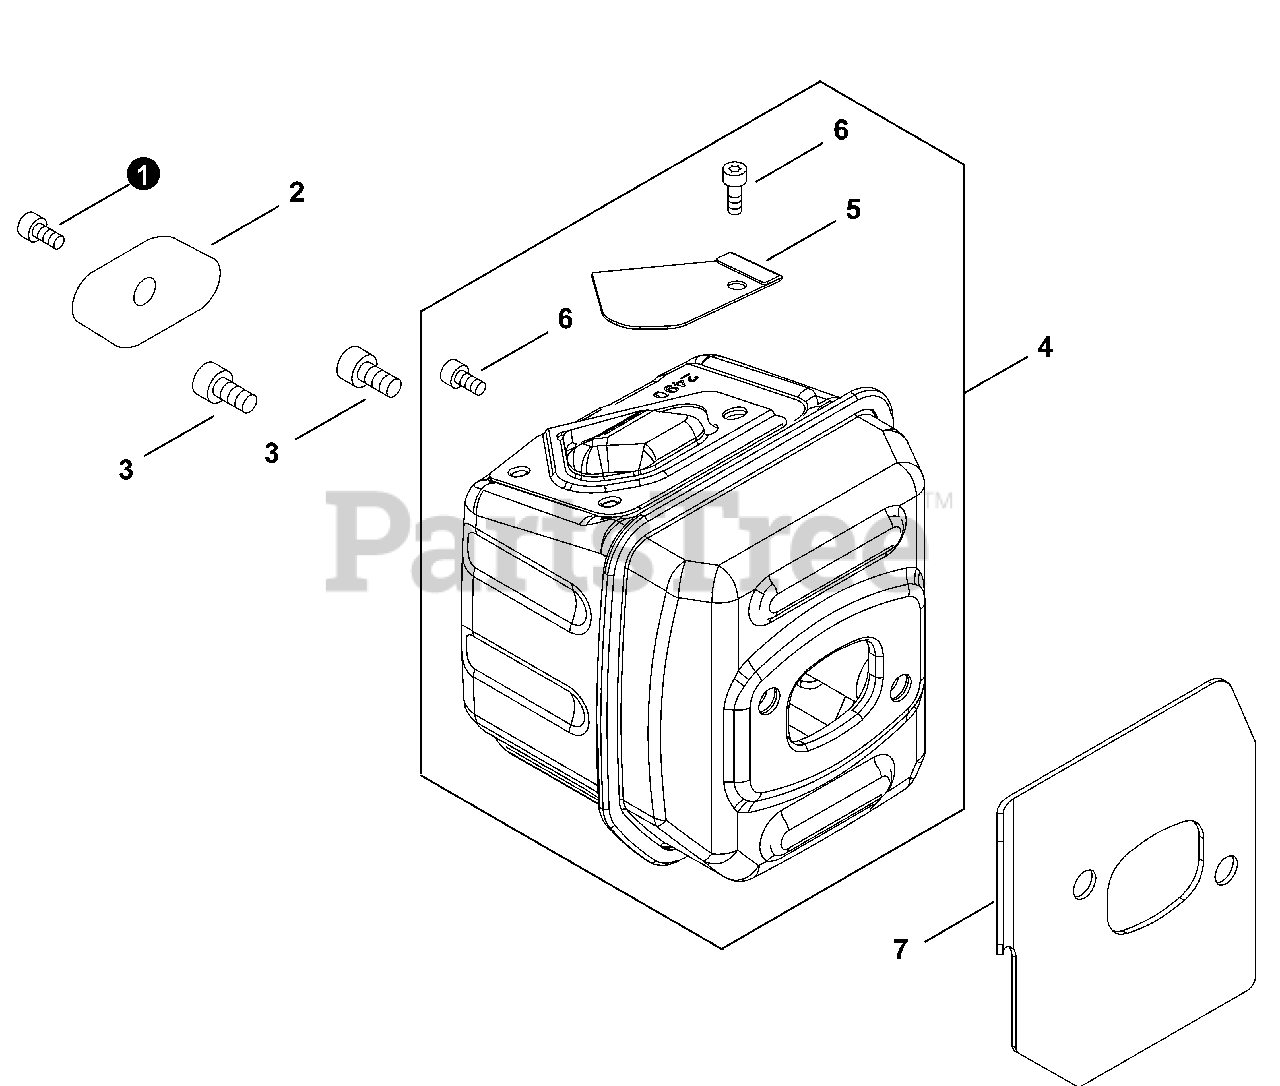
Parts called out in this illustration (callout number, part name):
1	BOLT, TORX 4×8
3	BOLT, TORX 5×16
4	MUFFLER ASSY
5	SCREEN, SPARK ARRESTER
6	BOLT, TORX 4×8
7	GASKET, EXHAUST
